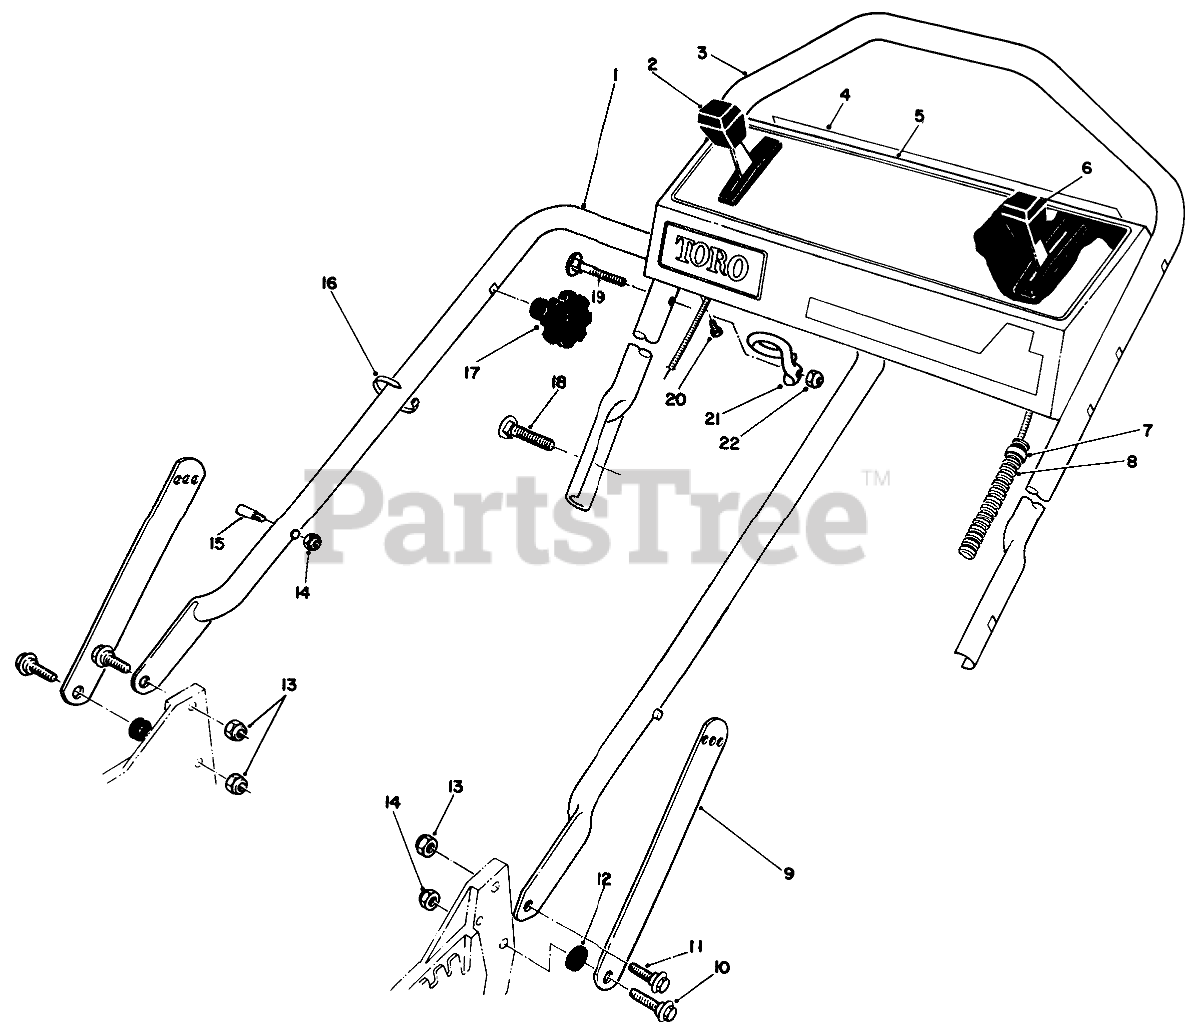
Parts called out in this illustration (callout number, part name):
1	LOWER HANDLE ASM
2	Control-Ground Speed
3	UPPER HANDLE
4	DECAL-PANEL, DANGER
5	Panel-Control (Incl. Ref. #4)
6	THROTTLE CONTROL - R&S
7	FITTING-RING
8	CONTROL CABLE COVER
9	Handle Latch
10	SCREW-SHOULDER
11	SCREW-SHOULDER
12	SPACER
13	NUT-LOCK, NI
14	NUT-LOCK, NI
15	HANDLE PIN
16	TIE-CABLE
18	5/16-18 X 2 HNDLE SCREW
19	HANDLE SCREW
20	SCREW-HWHTF
21	Guide
22	NUT-LOCK, NI
